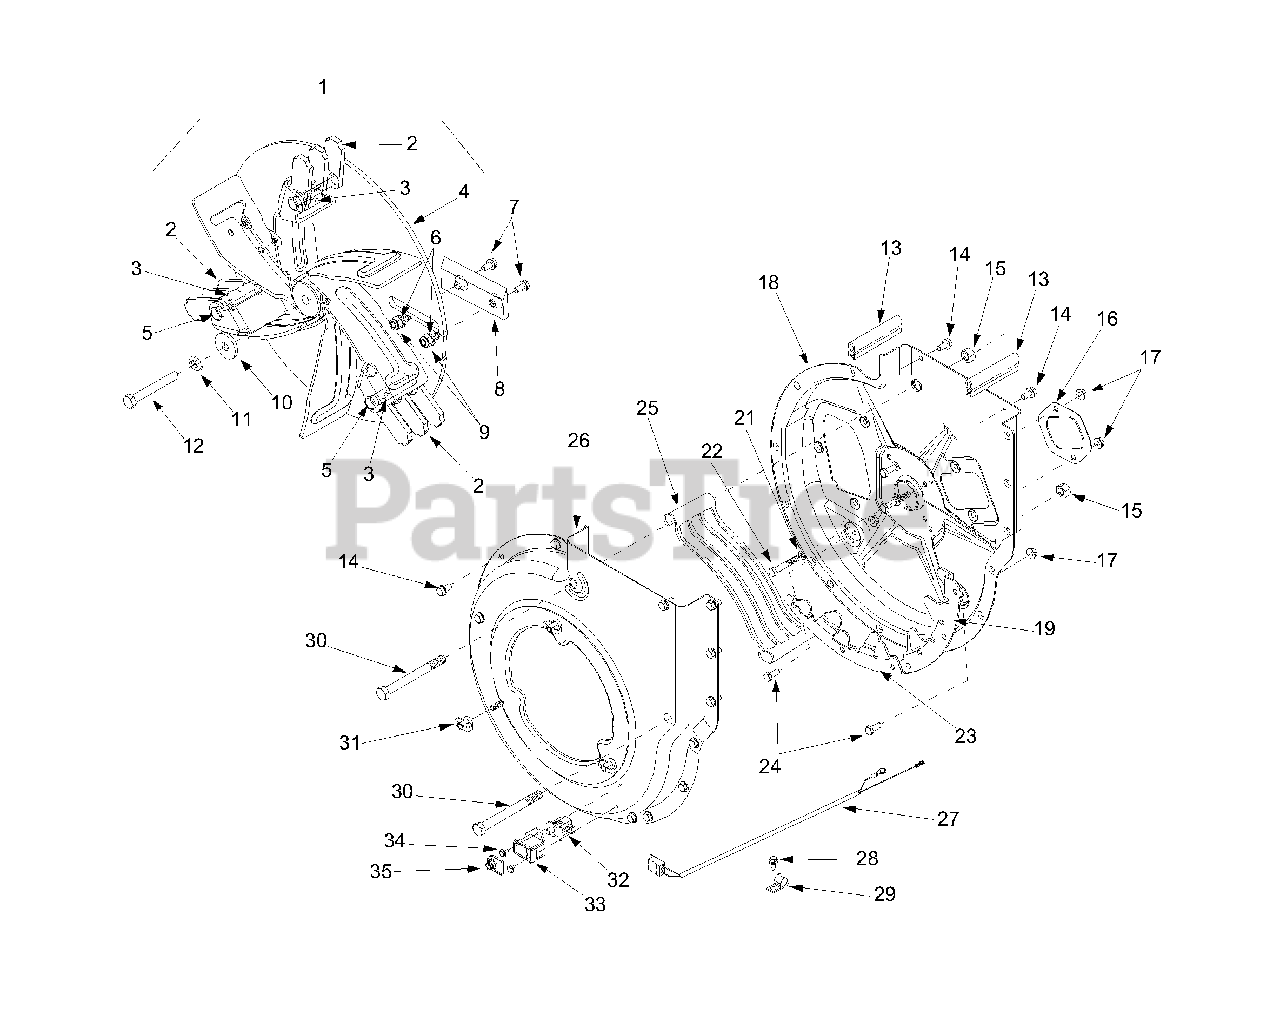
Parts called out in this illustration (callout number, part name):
1	Impeller Ass'y Complete
2	Flail Blade
3	Spiral Pin
4	Impeller Assembly
5	Clevis Pin
6	Lock Washer 5/16
7	Cap Screw 5/16-24 x 1.0
8	Chipper Blade
9	Hex Lock Nut 5/16-24
10	Flat Washer .406 x 1/1/4
11	Lock Washer 3/8
12	Hex Cap Screw 3/8-24 x 2.75
13	Rubber Seal
14	Hex Washer Screw 5/16-18
15	Hex Lock Nut 1/2-13
17	Hex Flange Lock Nut 5/16-18
21	Lock Washer 5/16
22	Hex Cap Screw 5/16-18 x 2
24	Hex Cap Screw 5/16-18 x .75
25	Discharge Screen
27	Wire Harness
28	Hex Washer Screw 1/4-14
30	Hex Cap Screw 1/2-13 x 5.0
31	Knob 5/16-18
32	Switch
33	Safety Switch Mounting Cover
34	Hex Washer Screw
35	Switch Cover
